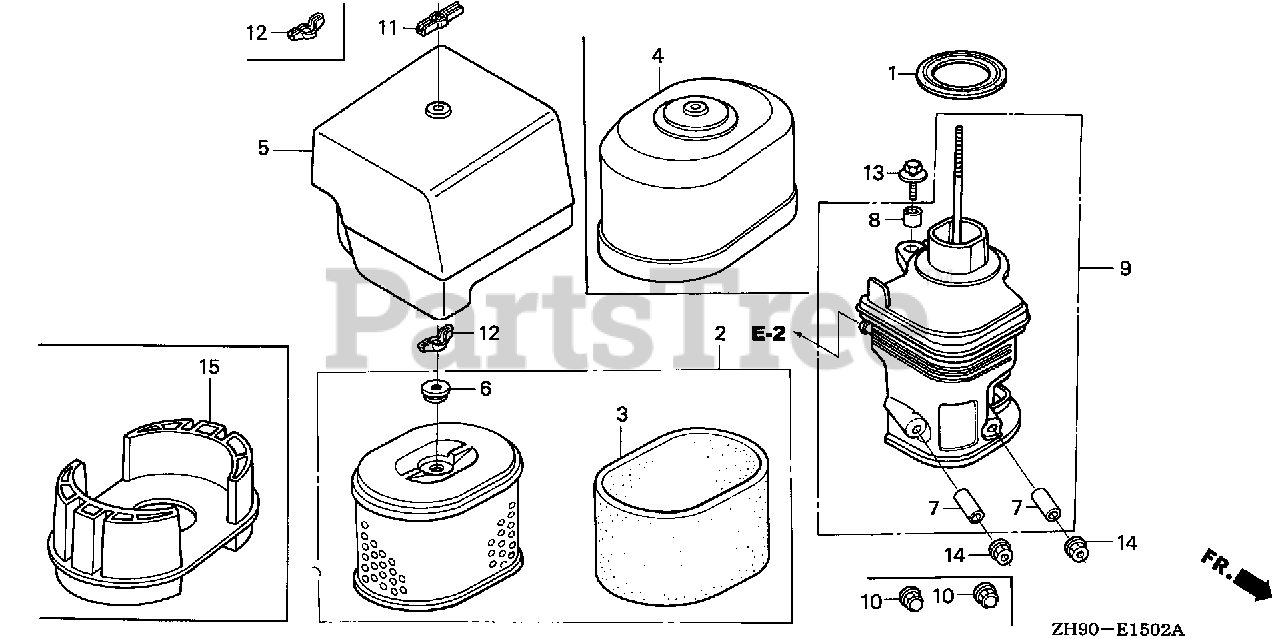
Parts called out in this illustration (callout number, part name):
1	GASKET, ELBOW
2	ELEMENT, AIR CLEANER (DUAL)
3	FILTER (OUTER)
5	COVER, AIR CLEANER
6	GROMMET, AIR CLEANER
7	COLLAR, AIR CLEANER
8	COLLAR B, AIR CLEANER
9	ELBOW, AIR CLEANER
10	NUT, CAP (6MM)
11	WINGNUT (6MM) (BLACK)
12	NUT, TOOL BOX SETTING
13	BOLT-WASHER (6X20)
